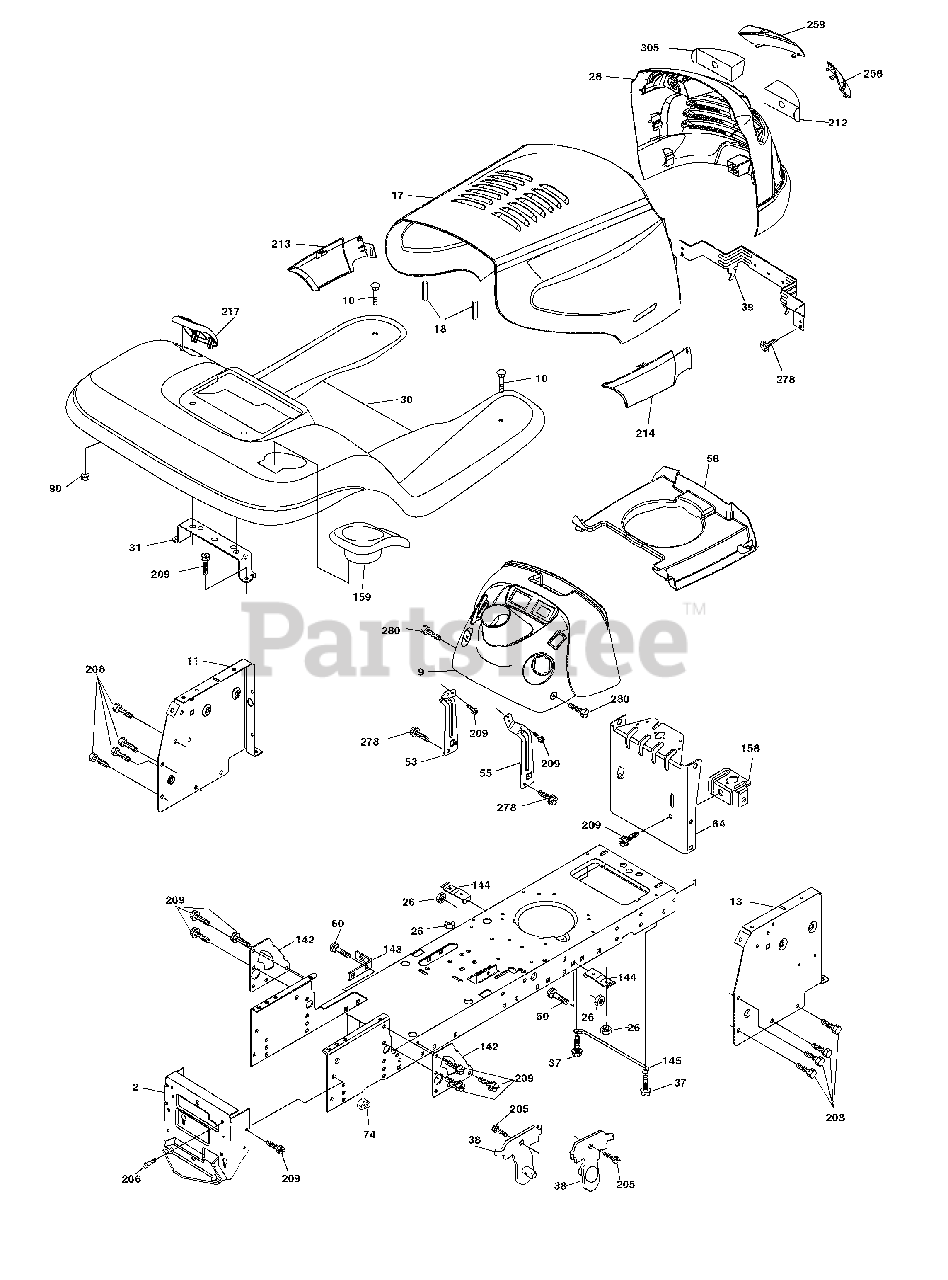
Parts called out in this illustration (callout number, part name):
1	Chassis
10	Bolt Carriage 3/8-16 x 1
11	Panel Dash LH
13	Panel Dash RH
17	Hood
18	Bumper Hood
26	Nut Lock Hex w/Ins 3/8-16 unc
28	Grille/Lens Asm.
30	Fender Footrest
31	Bracket Fender
37	Screw Thdrol 6/16-18 x 1/2 TYT
38	Bracket Asm Pivot Mower Rear
39	Bracket Pivot Hood
53	Bracet Dash LH
55	Bracket Dash RH
60	Bolt RDHD Sqnk 3/8-16 unc x 3/4
64	Dash Lower STLT
74	Nut Crownlock 3/8-16 unc
90	Nut Self Thd Wsh - HD 1/4 Zinc
142	Plate Reinforcement STLT
143	Bracket Swaybar Chassis
144	Bracket Footrest Step-thru
145	Rod Pivot Hood
158	Bracket Parking Brake
159	Cupholder
205	Screw Thdrol 3/8-16 x 1/2
206	Bolt Shoulder 5/16-18
208	Screw Thdrl 3/8-16 x 1/2
209	Screw Hexwsh Thdr 3/8-16 x 3/4
212	Insert Lens
213	Skirt Grille LH
214	Skirt Grille RH
217	Console Fuel Window
258	Lens RH
259	Lens LH
278	Screw #10 x .0750
280	Screw 3/8-16 x 1
305	Insert Lens LH
